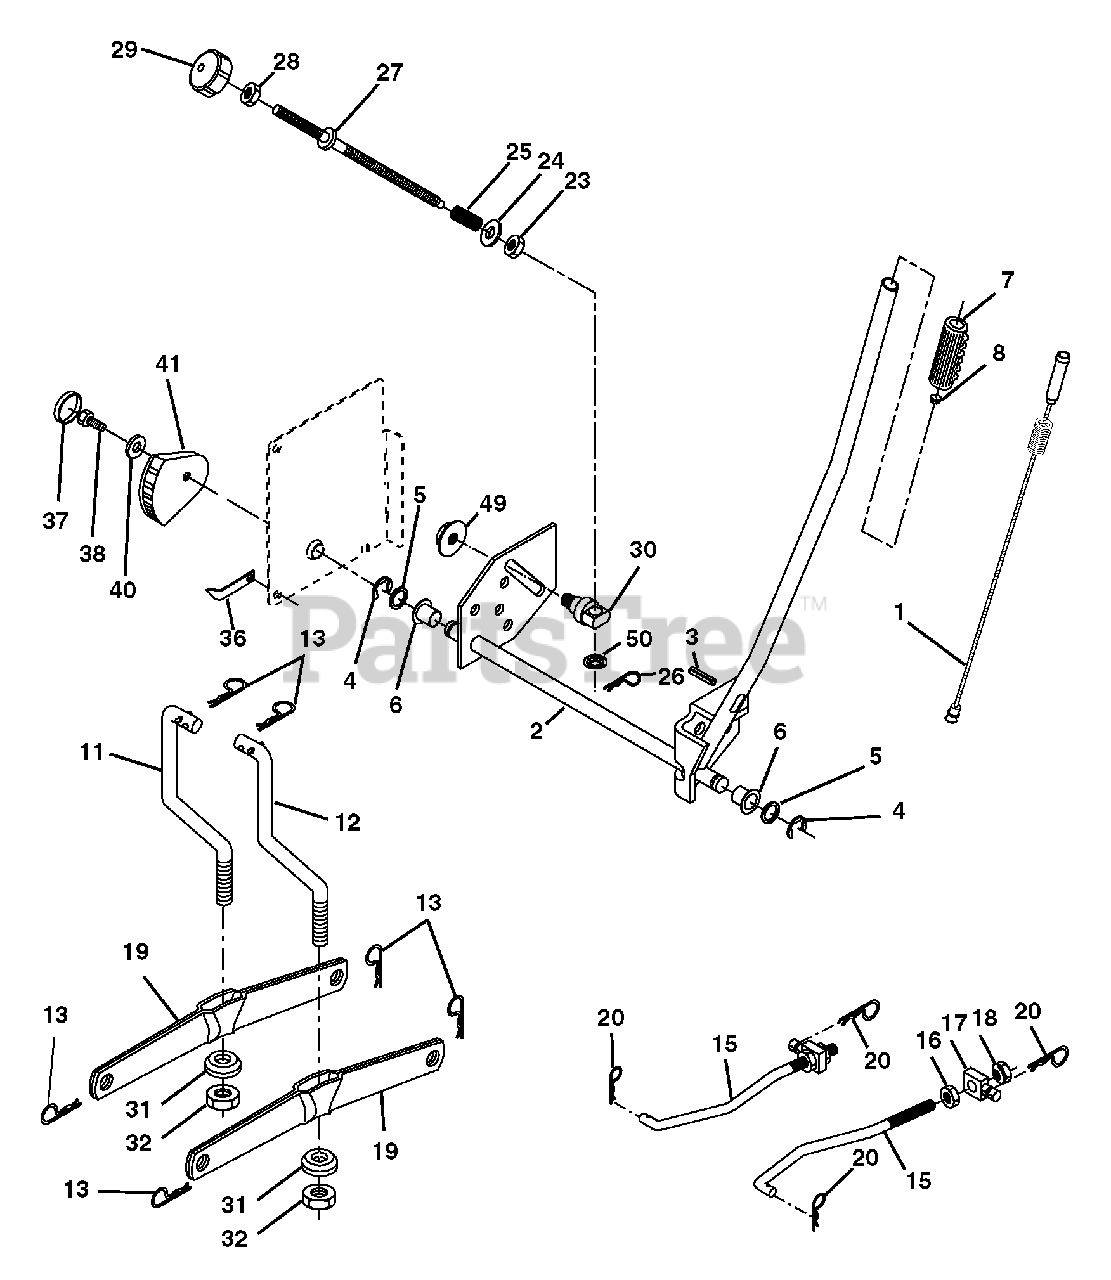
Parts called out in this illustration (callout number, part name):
1	Lift Lever Inner Wire Assembly
2	Shaft Assembly, Lift
3	Pin, Groove
5	Washer 21/32 x 1 x 21 Gauge
6	Bearing, Nylon
7	Grip, Handle
8	Button, Plunger
11	Link, Lift, L.H.
12	Link, Lift, R.H.
13	Retainer Spring
15	Link, Front
16	Nut, Hex, Jam 1/2-13 Unc
17	Trunnion
18	Locknut, Hex, with Washer Insert 1/2-13 Unc
19	Arm, Suspension, Rear
20	Retainer Spring
23	Nut Special
24	Washer 13/32 x 5/8 x 16 Ga.
25	Spring 2-1/8
26	Retainer Clip
27	Rod Adj. Lift
28	Nut Hex Jam 3/8-16
29	Knob Inf. 3/8-16
30	Trunnion Infin. Height
31	Bearing, Pvt, Lift
32	Nut, Crownlock 3/8-24
36	Pointer Height Indicator
37	Plug Hole
38	Screw 5/16-18 x 1
40	Washer 11/32 x 1-1/2 10 Ga.
41	Indicator Height
49	Nut Hex Flange Lock
50	Nut Push Phos. & Oil
